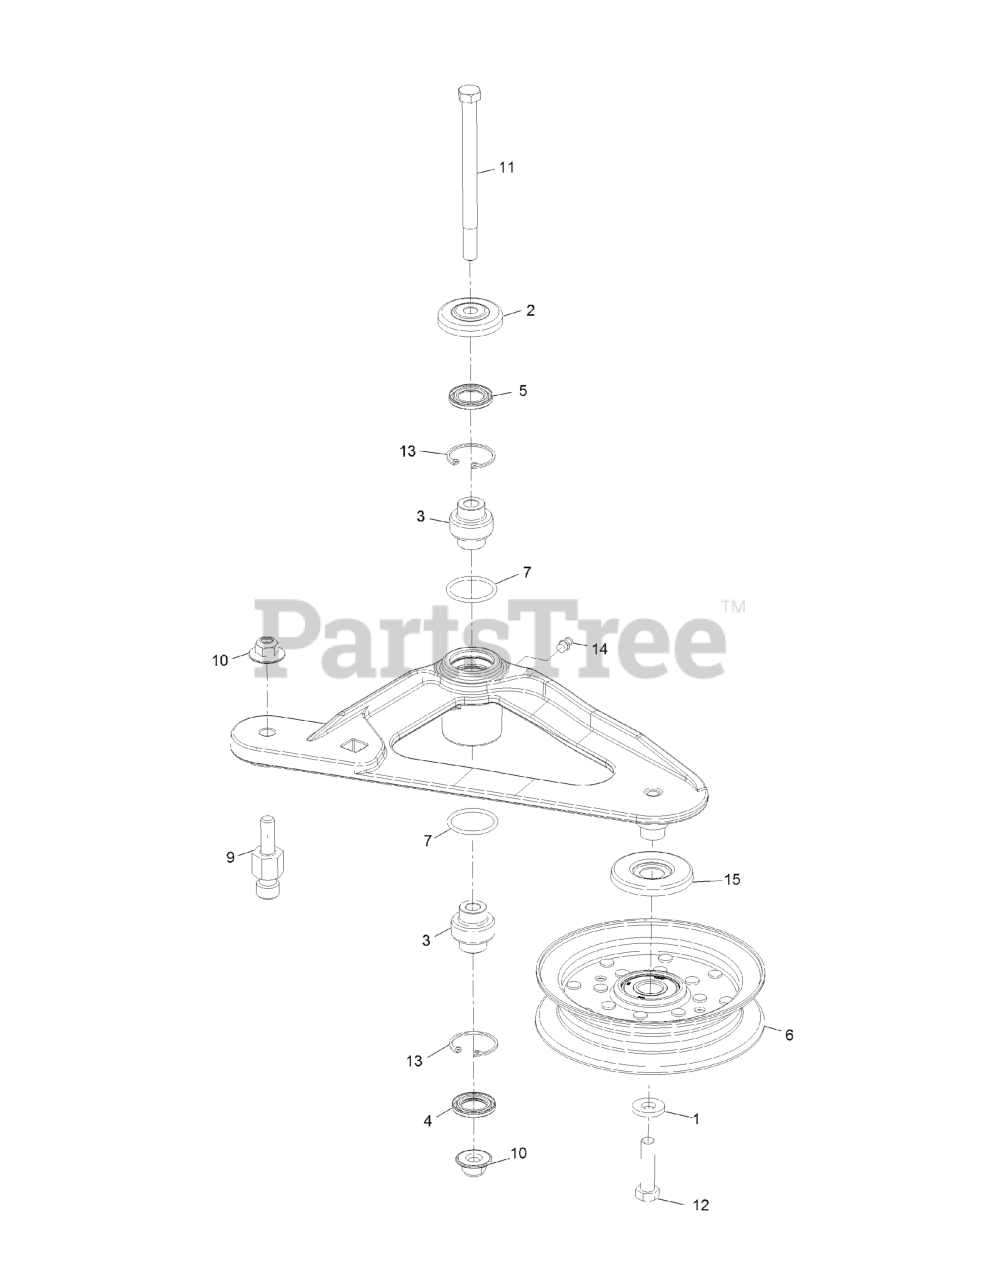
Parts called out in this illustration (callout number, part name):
2	GUARD-TOP
3	BEARING-SPHERICAL
4	SEAL-LIP, DOUBLE
5	SEAL-LIP, SINGLE
6	IDLER-PULLEY, FLAT
9	PIN-SPRING, ANCHOR
10	Nut-Nyloc 3/8-16 Flg
11	SCREW-SHOULDER, HH
12	SCREW-HH
13	RING-SNAP
14	FITTING-GREASE
15	SHIELD-GUARD, DUST
